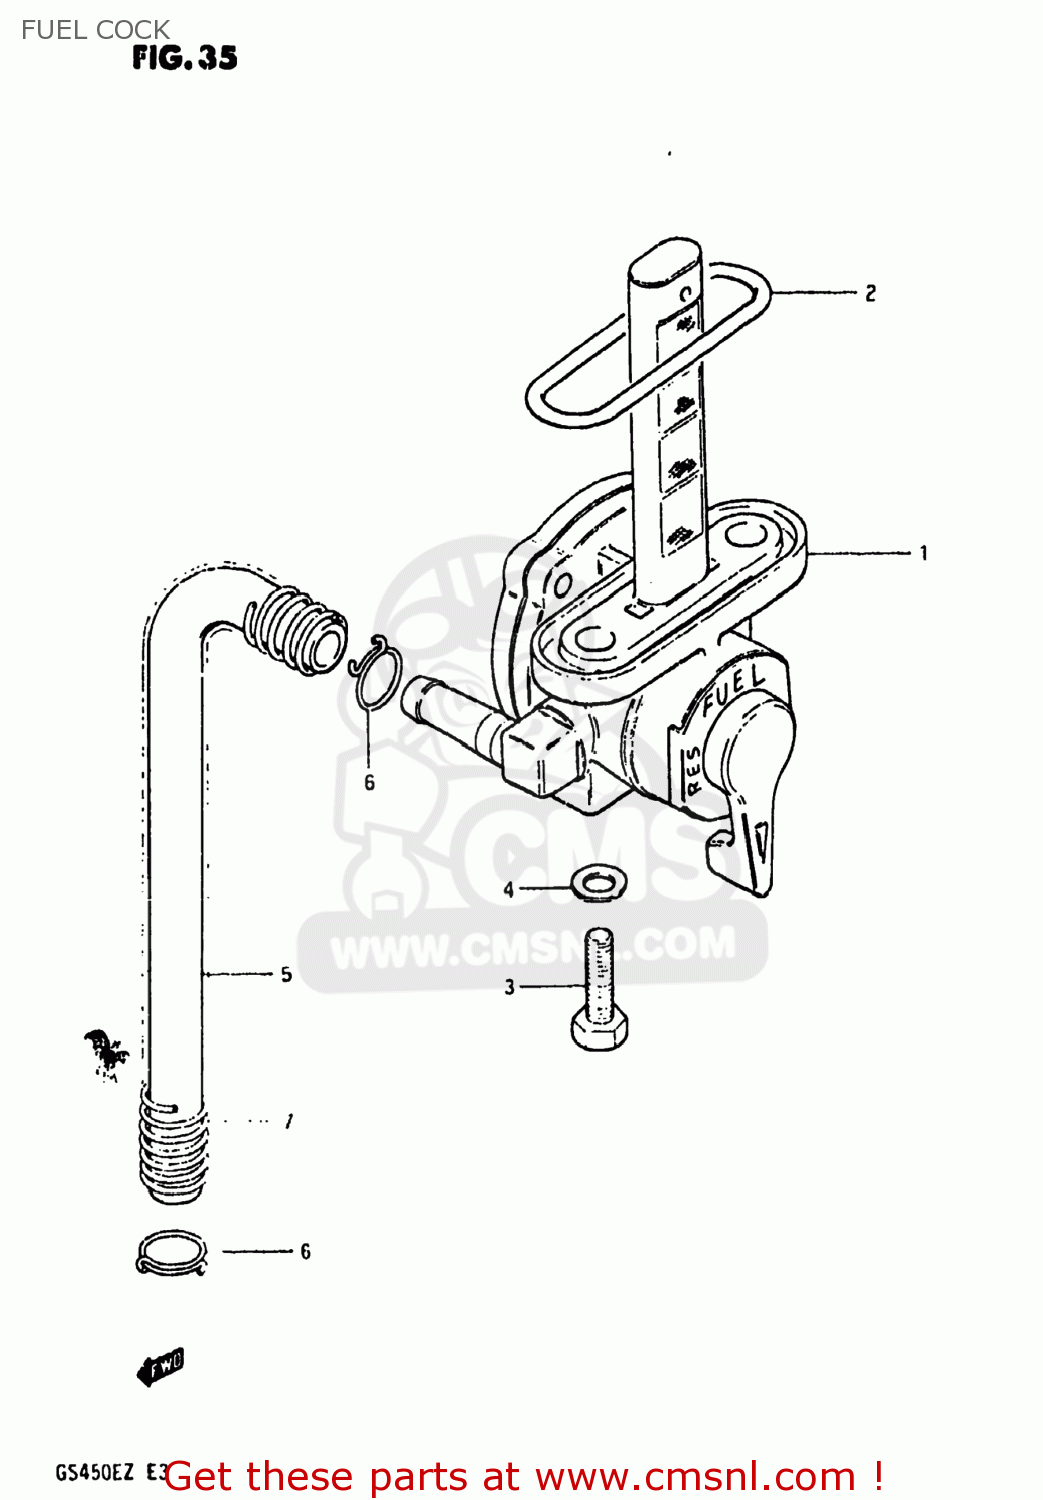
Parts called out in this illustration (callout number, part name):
1	COCK ASSEMBLY,FUEL
2	O RING
3	SCREW
4	GASKET
5	HOSE
6	CLIP
7	SPRING
